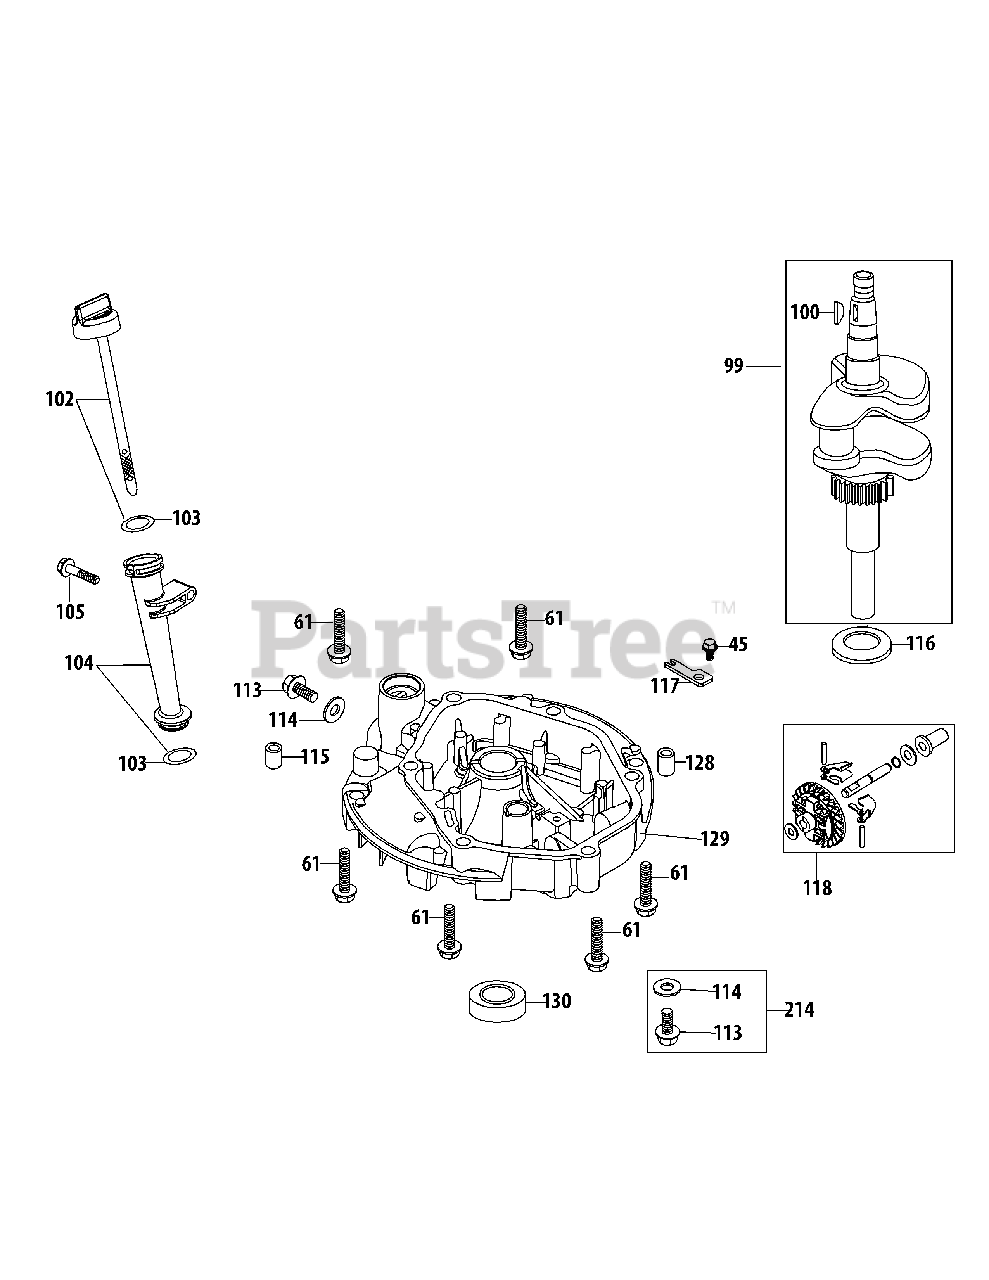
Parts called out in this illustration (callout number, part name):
45	Bolt M6X14
61	Bolt M8X50
99	Crankshaft Assembly
100	Flywheel Key
102	Dipstick Assembly
103	Oil Fill Tube O-Ring
104	Oil Filler Tube Assemlby
105	Bolt M6X35
113	Oil Drain Plug
114	Oil Drain Plug Washer
115	Crankcase Cover Dowel Pin 9×14
116	Crankshaft Thrust Washer
117	Governor Gear Mounting Plate
118	Governor Gear/Shaft Assembly
128	Crankcase Cover Dowel Pin 7×14
129	Crankcase Cover
130	Lower Crankshaft Seal
214	Oil Drain Plug And Washer Assy
